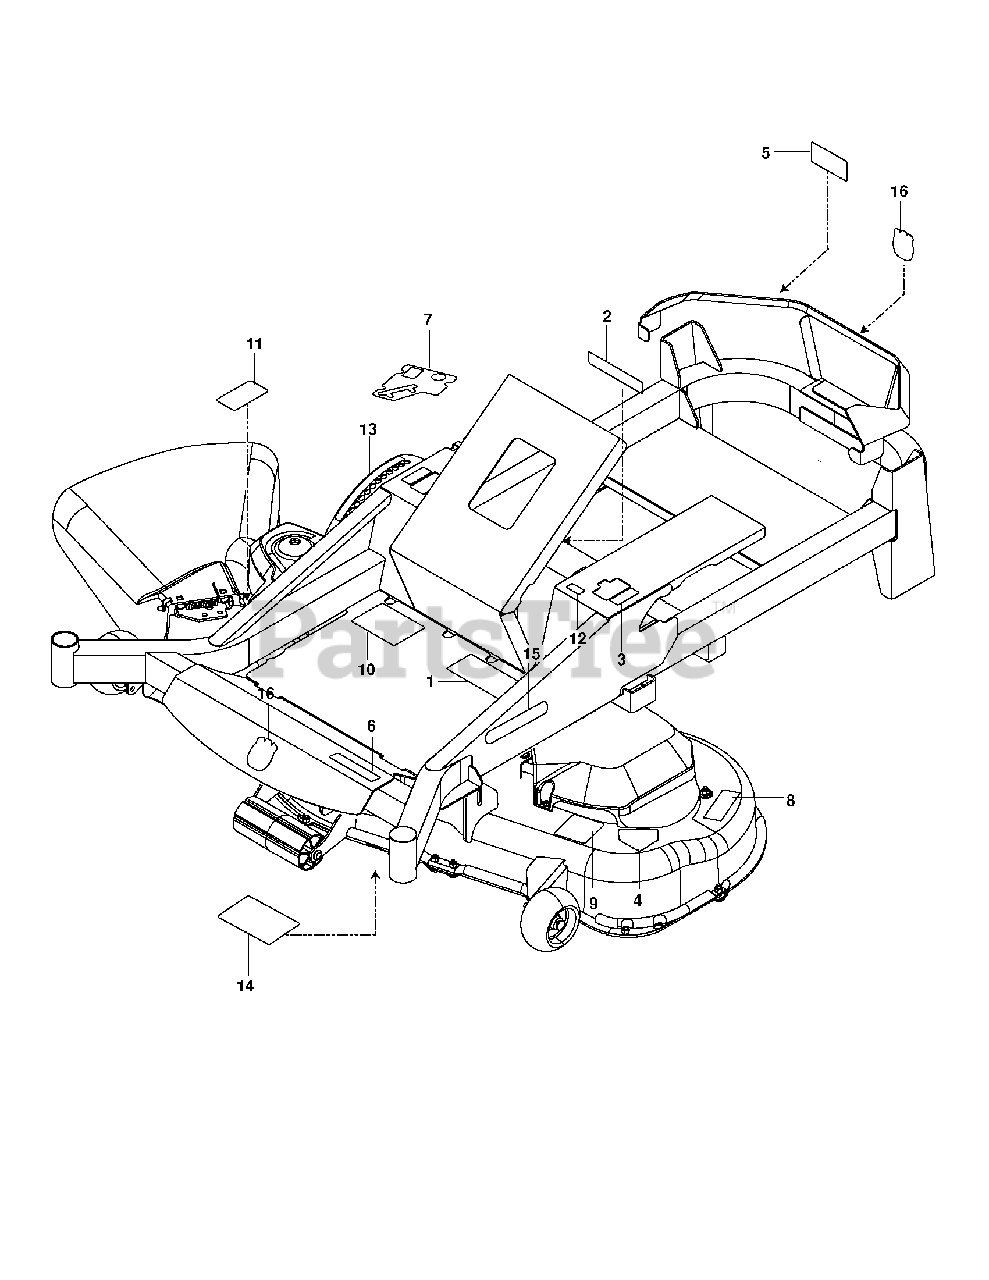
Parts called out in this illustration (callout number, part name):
1	DECAL, WARNING
2	EURO DECAL-BATTERY WARNIN6
3	DECAL, MOTION CONTROL
4	DECAL, CPSC
5	DECAL, BELT DRIVE
6	DECAL, MZ5424S
7	DECAL, CONSOLE HUS
8	DECAL, EURO SEVERING
9	DECAL, BELT ROUTING
10	DECAL, WARNING
11	DECAL.DECK.6MIL./DEF.SHLD.WARN
12	DECAL, F.S.T.
13	DECAL, HEIGHT ADJUST
14	DECAL, SERVICE
15	RP.DECAL.BADGE.170MM.TEXTLOGO
16	DECAL.AUGER.HUSQ.CROWN.SNOW
